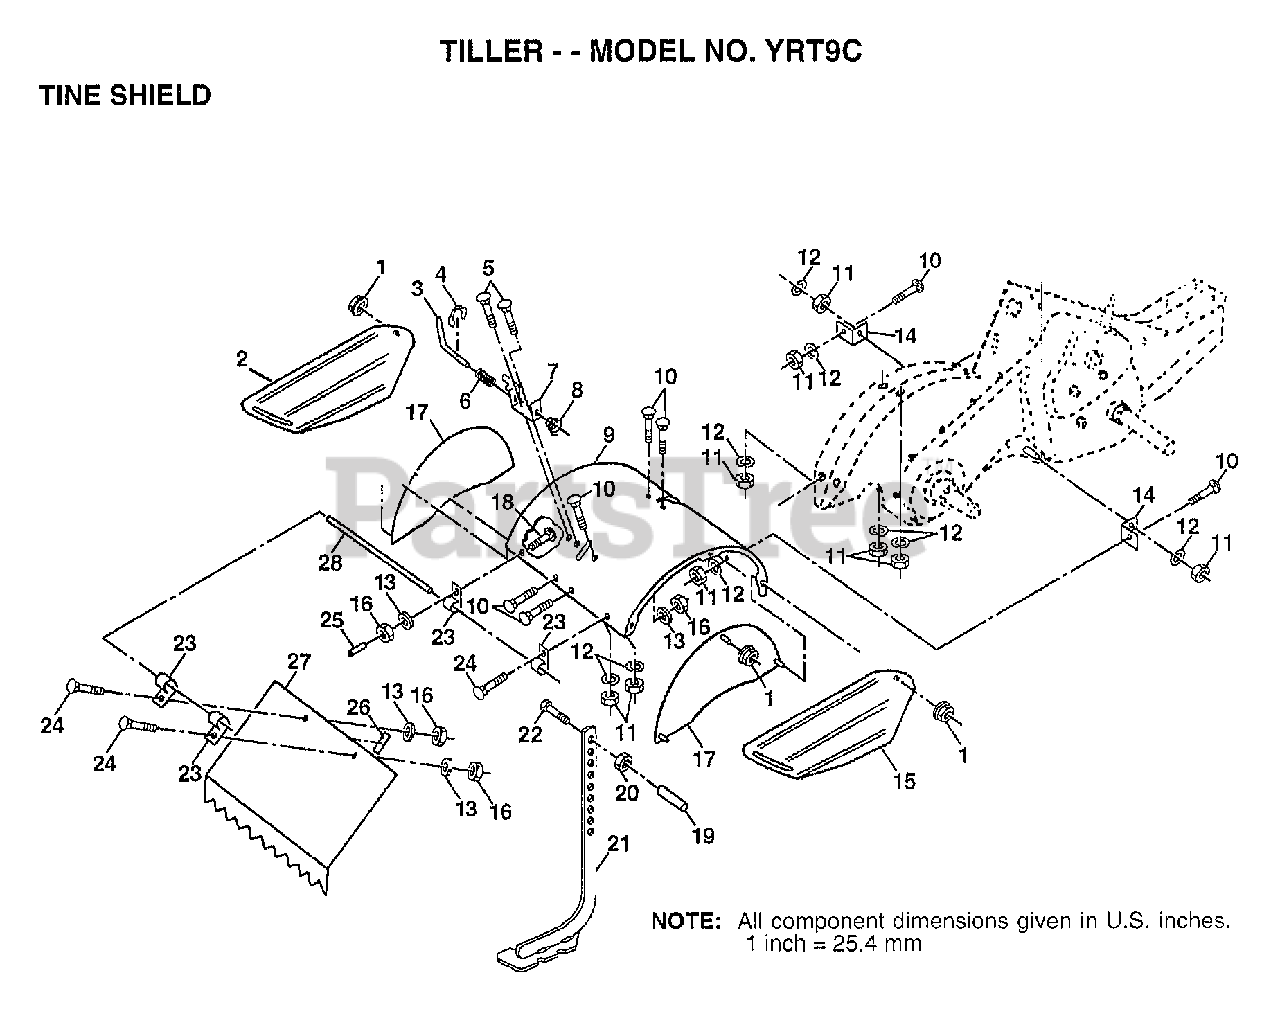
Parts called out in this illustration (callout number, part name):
1	NUT
2	SHIELD.SIDE.OUTER.LH
3	STAKE PIN TI
4	KLIP RING TI
5	BOLT
6	SPRING TI
7	LATCH BRACKET TI
8	SPRING CRT
9	SHIELD TINE
10	BOLT
11	NUT.HEX.5/16-18
12	LOCKWASHER
13	LOCKWASHER
14	TINE SHLD BRKT TI
15	SHIELD.SIDE.OUTER.RH
18	BOLT
19	GRIP CRT
20	NUT.HEX.3/8-16UNC
21	STAKE.ASM.DEPTH
22	BOLT
23	HINGE CRT
24	BOLT.1/4-20X1/2
25	VINYL CAP TI
26	PAD IDLER TI
27	SHIELD LEVELING
28	PIN.HINGE
